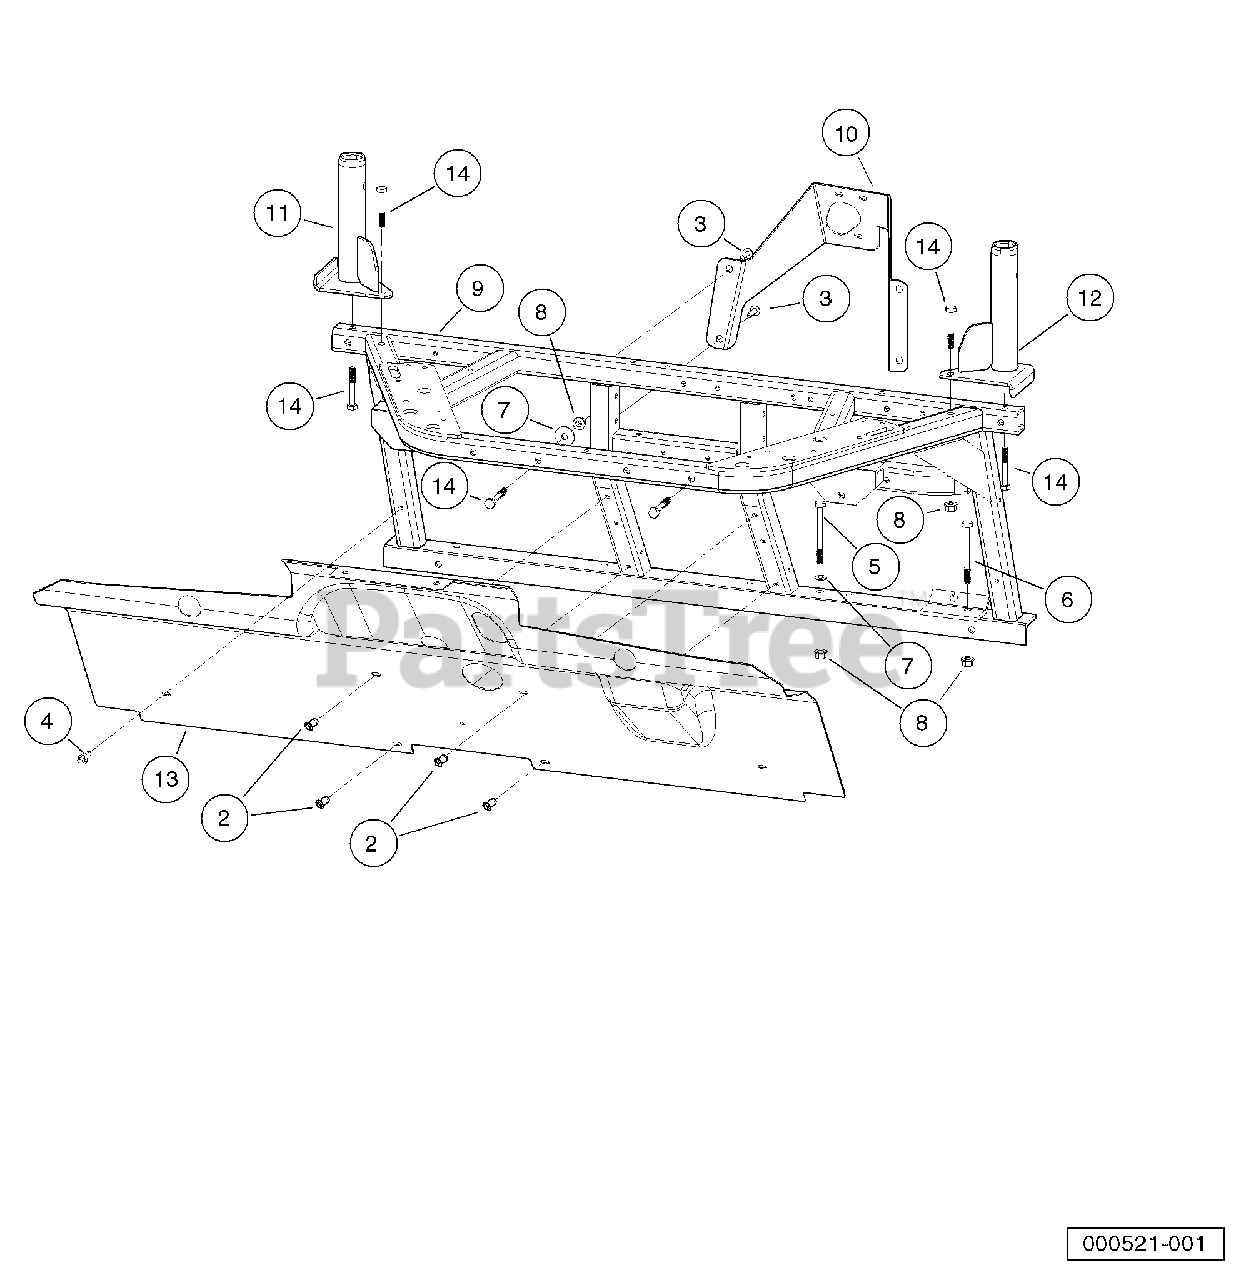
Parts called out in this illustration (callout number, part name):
1	Instl, Cowl Weldmnt/Splash Guard
2	Blind Rivet, Push Type
3	Screw, M8X1.25X30, Hex
4	M8-1.25x20 Taptite
5	Bolt, M10x1.50x100
6	Bolt, M10 X 1.50 X 110 Black
7	Washer Hard,m10
8	Nut Flg M10 X 1.5 Mech Def
9	Weldment, Dash, Front
10	Bracket, Column, Steering
11	Weldment, Front, Base, ROPS, Right-Hand
12	Weldment, Front, Base, ROPS, Left-Hand
13	Guard, Splash, Gas Injection
14	Bolt, M10 X 1.50 X 65
